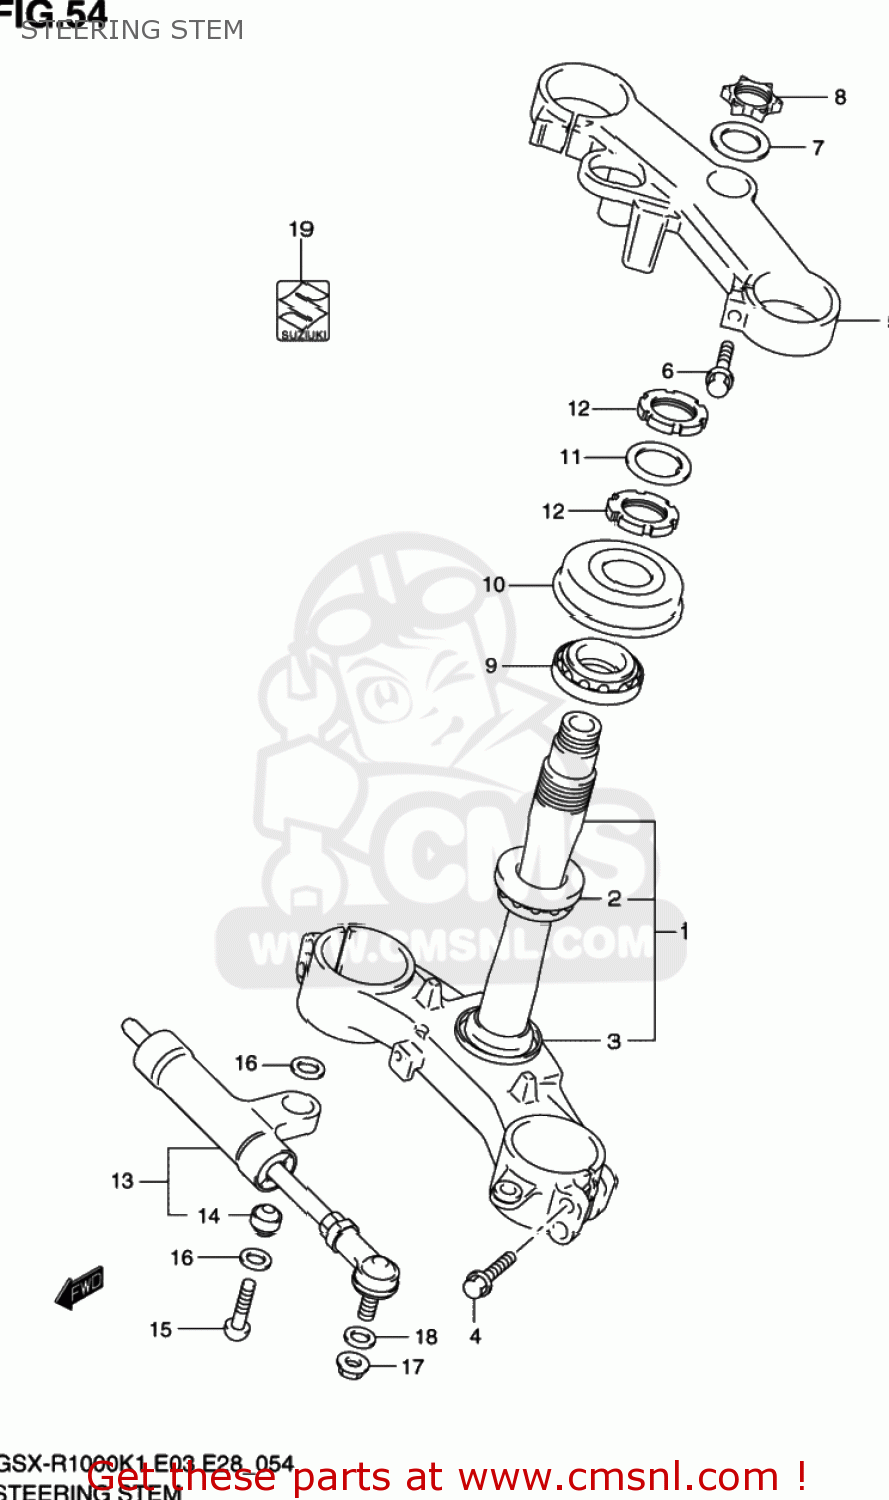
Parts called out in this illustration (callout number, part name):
1	BRACKET,FR FORK UNDER
2	BEARING(30X55X17)
3	SEAL,STEERING LWR
4	BOLT
5	BRACKET,FR FORK UPR
6	BOLT
7	WASHER,STEM HEAD(24.5X34X1.6)
8	NUT
9	BEARING(30X55X17)
10	SEAL,STEERING UPR DUST
11	WASHER,STEERING STEM
12	NUT,STEERING STEM
13	DAMPER ASSY,ST
14	BEARING(8X17.5X11)
15	BOLT(8X35)
16	SEAL,PILLOW BALL,DUST
17	NUT
18	WASHER(8.5X18X1.6)
19	EMBLEM,S
